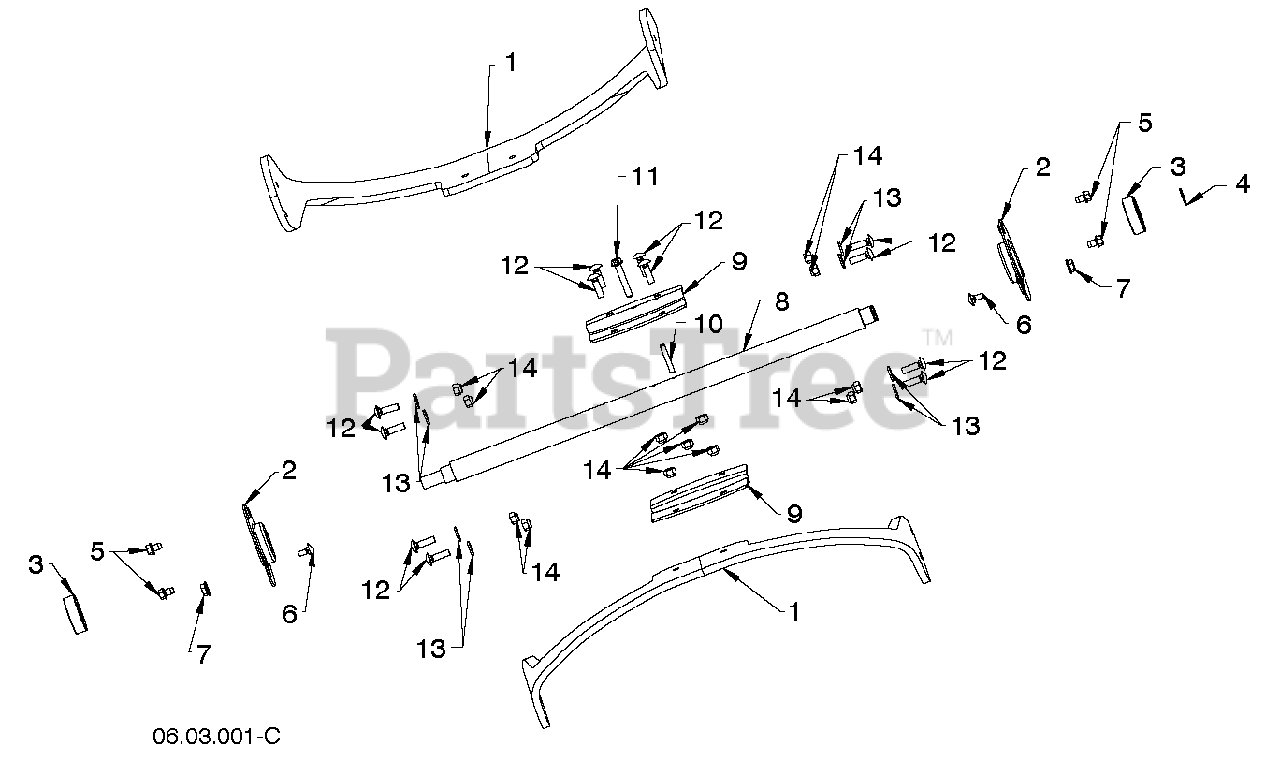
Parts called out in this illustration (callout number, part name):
1	AUGER.BLADE.SS.SNOW
2	SUPPORT.BEARING.SINGLE.STAGE.B
3	BEARING.BALL.MANDREL
4	RETAINING RING LT
8	WELDMENT.AUGER.SINGLE.STAGE.BL
9	PLATE.CENTER.BLADE.BLACK
10	PIN.ROLL.3/16 X 1-1/4
12	BOLT.CARRIAGE.1/4-20 X 7/8
13	WASHER
14	NUT
